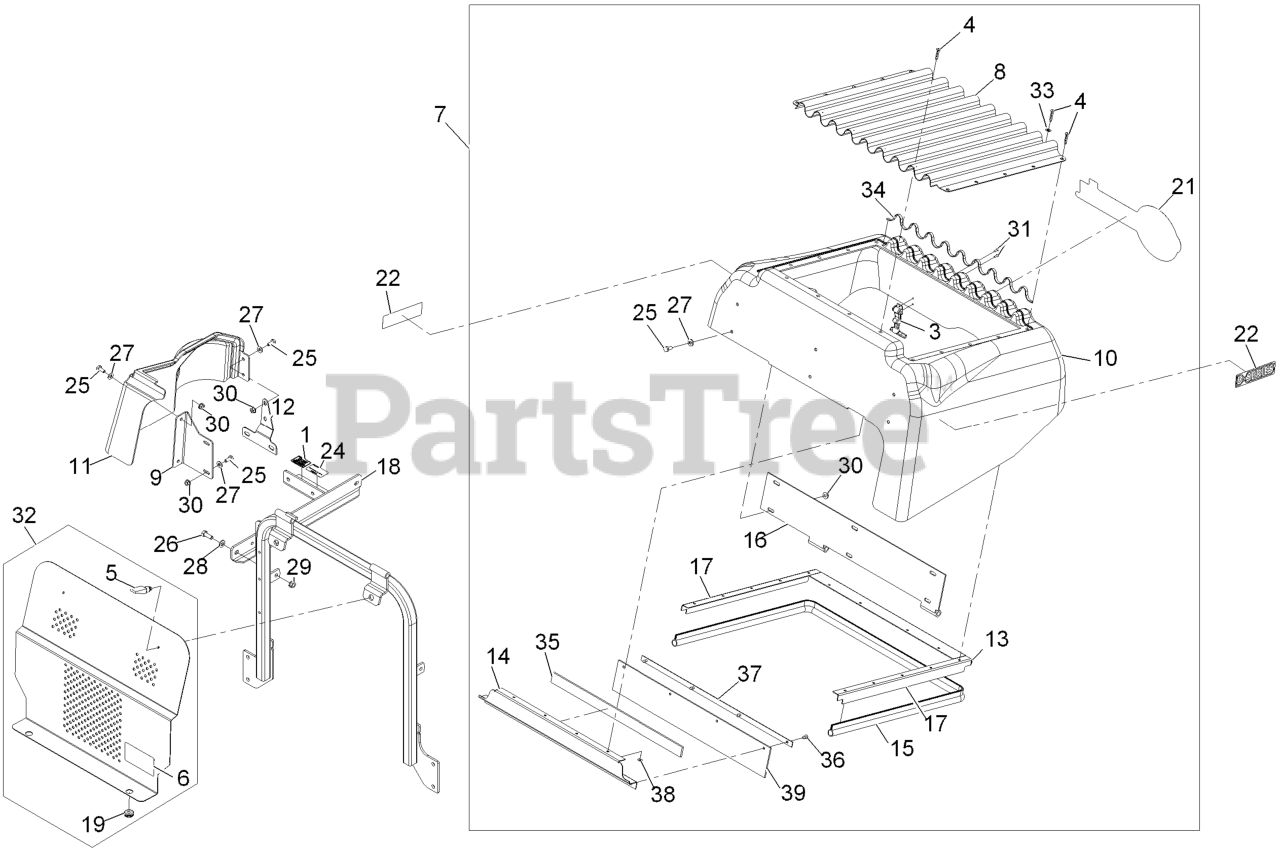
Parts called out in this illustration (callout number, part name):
3	LATCH-RUBBER
5	LATCH-SWELL
6	DECAL,HYDRO BELT ROUTING
8	SCREEN, RADIATOR
9	BRACKET,FRONT COVER
11	PANEL, SIDE
12	BRACKET,REAR COVER
13	MOUNT-SEAL REAR
14	MOUNT-SEAL FRONT
15	Seal-Trim 54.6
16	WLD, HINGE
17	MOUNT-SEAL SIDE
18	ASM,AIR CLNR BRKT W/DECAL
19	GROMMET
21	DECAL,EXMARK
22	DECAL-D-SERIES
24	DECAL-CAUTION
25	SCREW-HH
26	SCREW-HH
27	WASHER-FLAT
28	WASHER-PLAIN
32	ASM,AIR DEFLECTOR W/ DECA
33	WASHER-FLAT
34	SEAL-REAR SCREEN
35	SEAL-FRONT SCREEN
36	Pop Rivet.187X.188/.25Al(Ad64Abs)
37	PLATE-SEAL BACKUP
38	WASHER-SPRING
39	SEAL-RADIATOR HOOD
